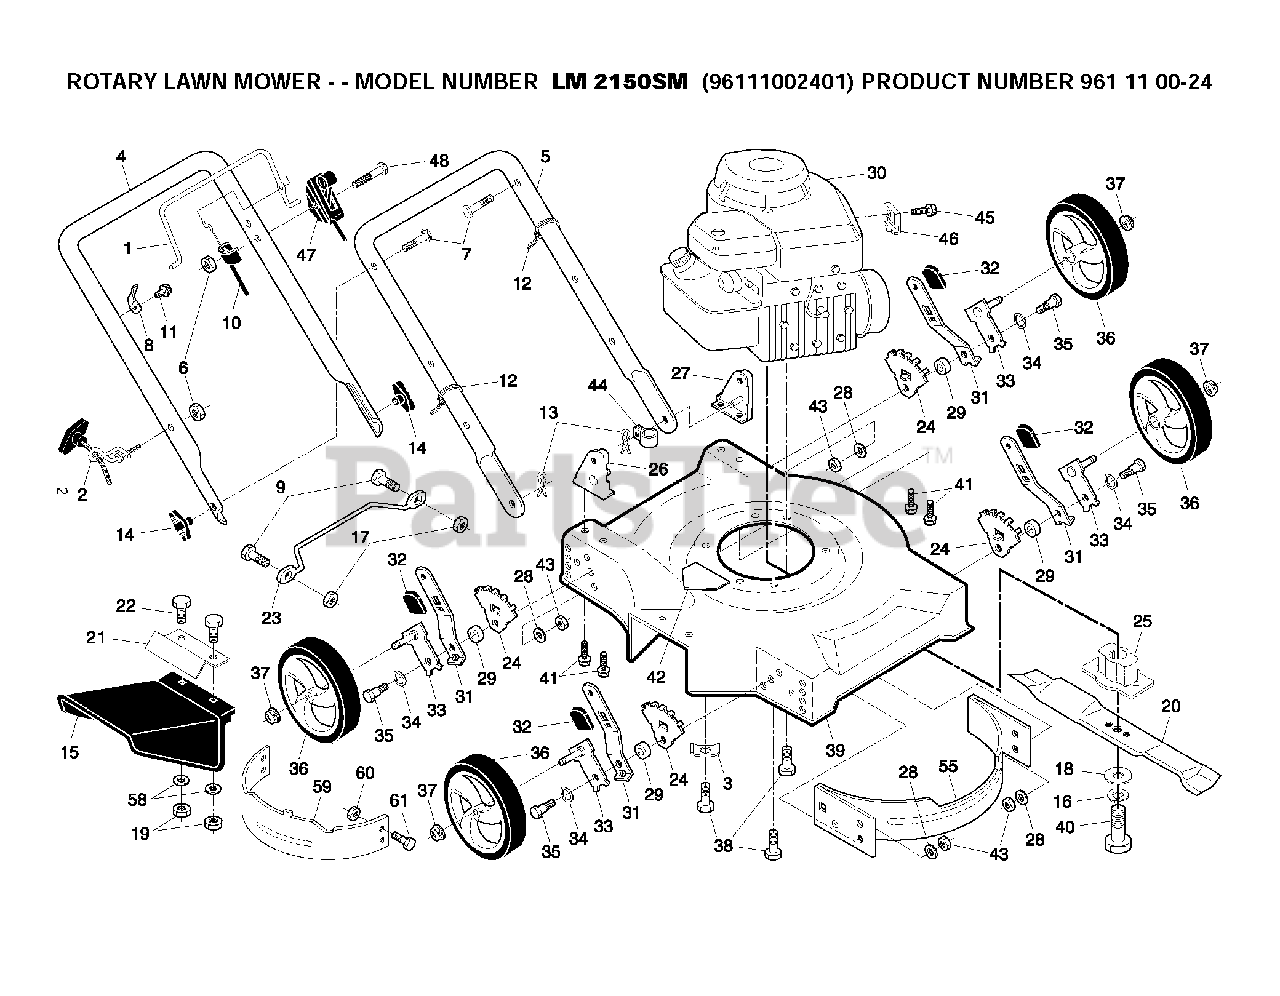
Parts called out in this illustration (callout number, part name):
2	GUIDE.ROPE.STD.BLK.ZIN
4	HANDLE.UPPER.FGD/PUSH.BLACK
6	NUT
7	BOLT, HANDLE 5/16-18X1.75
10	CABLE, CONT ENG
12	TIE GUIDE
13	HAIRPIN COTTER
14	KNOB, DEFLECTOR
16	LOCKWASHER
18	WASHER,HARDEN
19	LOCKNUT
20	BLADE.20.MULCH.(50DK,6020MD)
24	WHEEL ADJ BRACKET FRONT
25	BLADE ADAPTOR
26	HANDLE BRACKET ASM. RH
27	HANDLE BRACKET ASM. LH
28	WASHER
29	SPACER.HEIGHT.ADJUSTER
31	SELECTOR SPRING, FRONT
33	AXLE ARM ASSY.
34	WASHER FLAT
35	SHOULDER BOLT 5/16-18
37	NUT.HEX.FLANGE.3/8-16.LOCKNUT
38	BOLT 3/8-16X1-1/8
40	SCREW, HEX HD 3/8-24 X 1-3/8
41	SCREW 5/16-18
42	DECAL.INTERNATIONL.CUTFINGER
43	NUT.CENTERLOCK.5/16-
45	SCREW.HEX.HEAD.WASHER.10-16
46	CABLE CLAMP(ENGINE)
58	WASHER
59	CLOSEOUT PLATE
